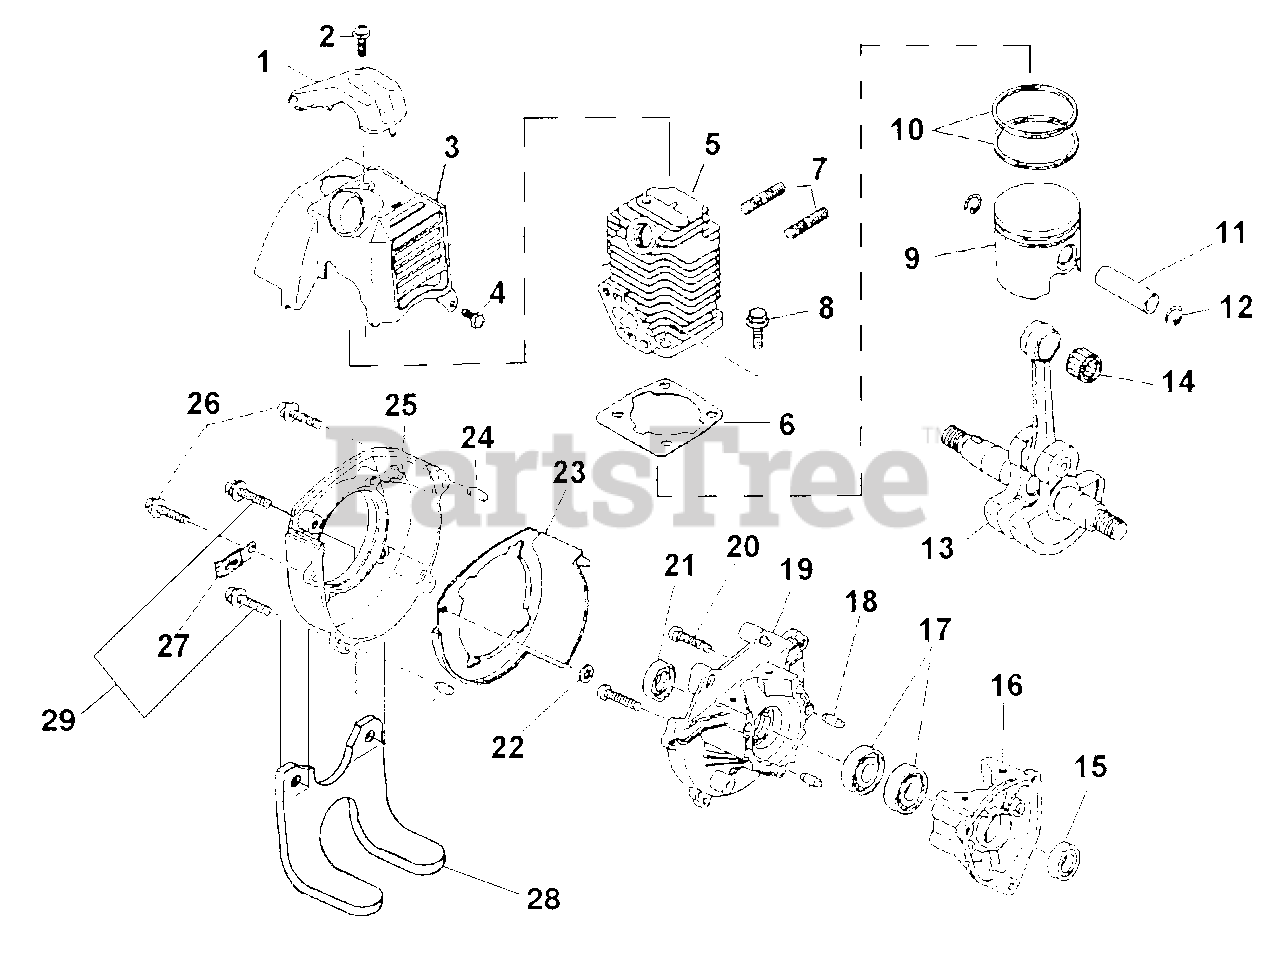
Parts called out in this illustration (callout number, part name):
1	GUARD, PLUG
2	SCREW & WASHER
3	COVER, TOP
4	SCREW & WASHER
5	CYLINDER ASSY (23cc)
5	CYLINDER ASSY (26cc)
6	GASKET, CYLINDER
8	SCREW & WASHER
9	PISTON ASSY (23cc)
9	PISTON ASSY (26cc)
10	RING, PISTON (23cc)
10	RING, PISTON (26cc)
11	PIN, PISTON
12	CLIP, PISTON PIN
12	CLIP, PISTON
13	CRANKSHAFT ASSY (23cc)
13	CRANKSHAFT ASSY (26cc)
14	BEARING, NEEDLE
15	OIL SEAL
16	CASE, STARTER
18	PIN, DOWEL
19	CASE, DRIVE
20	SCREW
21	OIL SEAL
24	PIN, DOWEL
25	CASE, FAN
26	BOLT & WASHER
28	ENGINE STAND
29	SCREW
